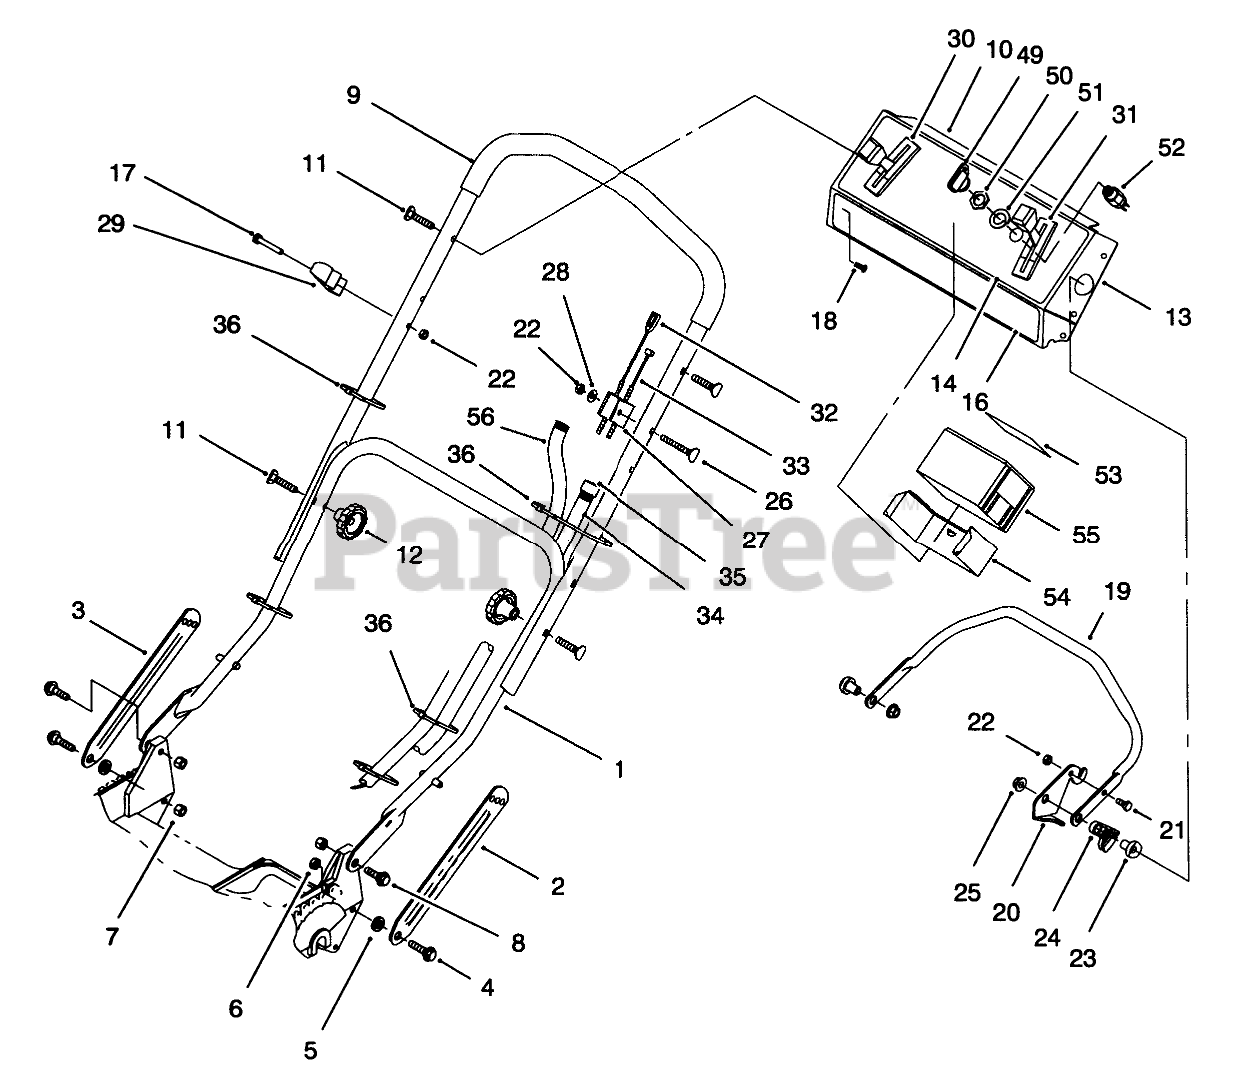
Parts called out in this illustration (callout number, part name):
1	ASM-Handle
2	Latch-Handle
3	Latch-Handle
4	SCREW-SHOULDER
5	SPACER
6	NUT-LOCK, NI
7	NUT-LOCK, NI
8	SCREW-SHOULDER
9	HANDLE - DIPPED
10	DECAL-PANEL, REAR
11	SCREW-HANDLE
13	Panel-Control (Incl. Ref. #10, 14)
14	DECAL - INSTRUCTION
16	DECAL - PANEL
17	.250-20X1.625 HH SCREW
18	SCREW-TAP
19	BAR-CONTROL
20	Lever-Control
21	SCREW-HH
22	NUT-LOCK, NI
23	SPACER-SUPPORT
24	LEVER-TRACTION
25	NUT-LOCK NI
26	SCREW-HANDLE
27	SUPPORT-CABLE
28	WASHER-FLAT
29	GUIDE-ROPE
30	CONTROL-SPEED, GROUND
31	THROTTLE CONTROL
32	BRAKE CONTROL
33	CABLE-TRACTION
34	CONTROL CABLE COVER
35	FITTING-RING
36	TIE-CABLE
49	KEY-IGNITION
50	NUT-HH
51	WASHER-TOOTH, INTERNAL
52	Switch-Starter (Incl. Ref. #50, 51)
53	DECAL-BATTERY
54	Retainer-Battery
55	BATTERY ASSEMBLY
56	WIRE HARNESS
